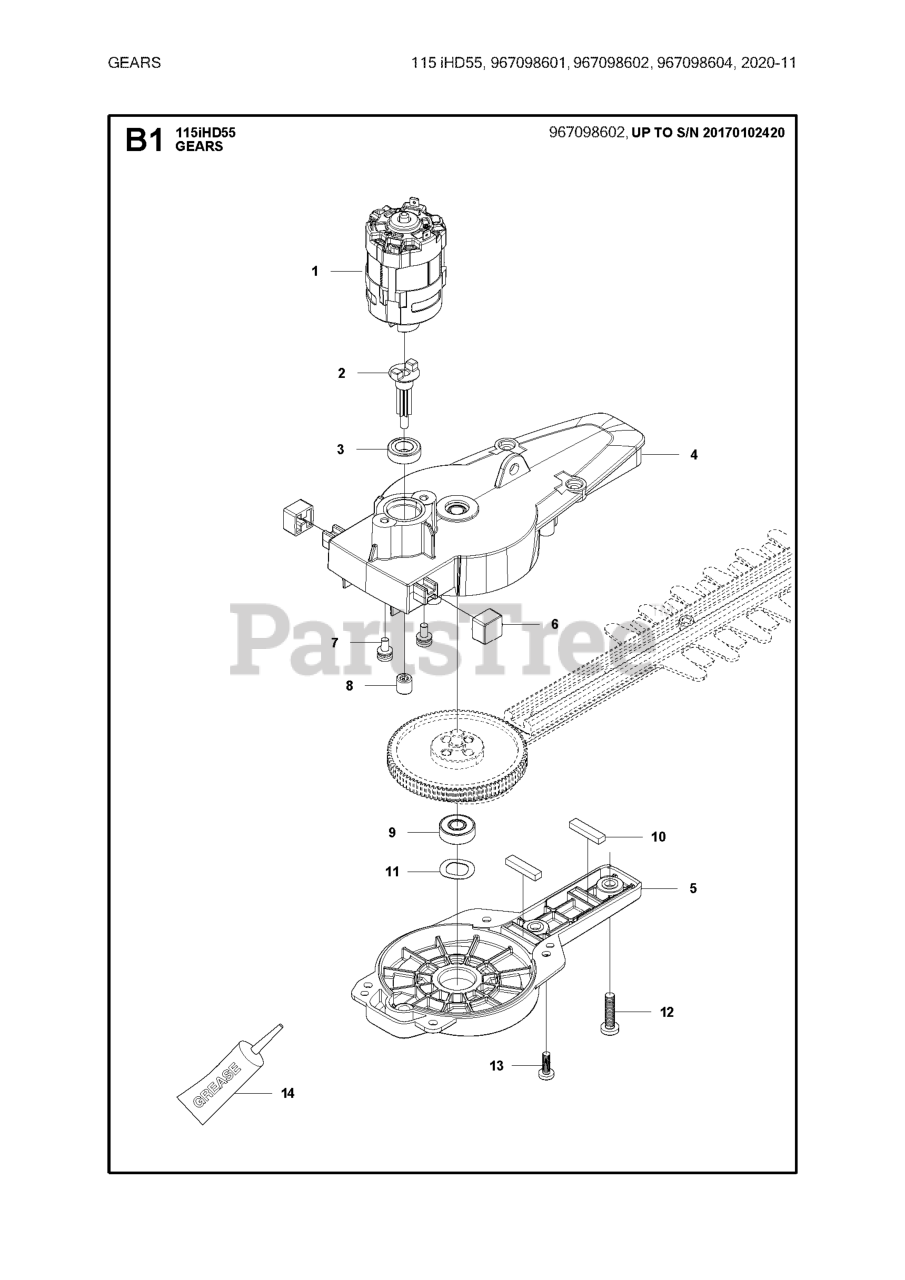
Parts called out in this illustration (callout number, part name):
1	MOTOR ASSEMBLY
3	BALL BEARING 689 2RS
4	GEAR BOX ASSEMBLY
5	COVER GEAR BOX
6	SHOCK ABSORBING
7	SCREW M3X10
8	NEEDLE BEARING
9	BALL BEARING
10	PAD DUSTPROOF
11	SPRING WASHER
12	SCREW M5X20
13	SCREW M4X12
14	GREASE 20G HEDGE TRIMMER GEAR
